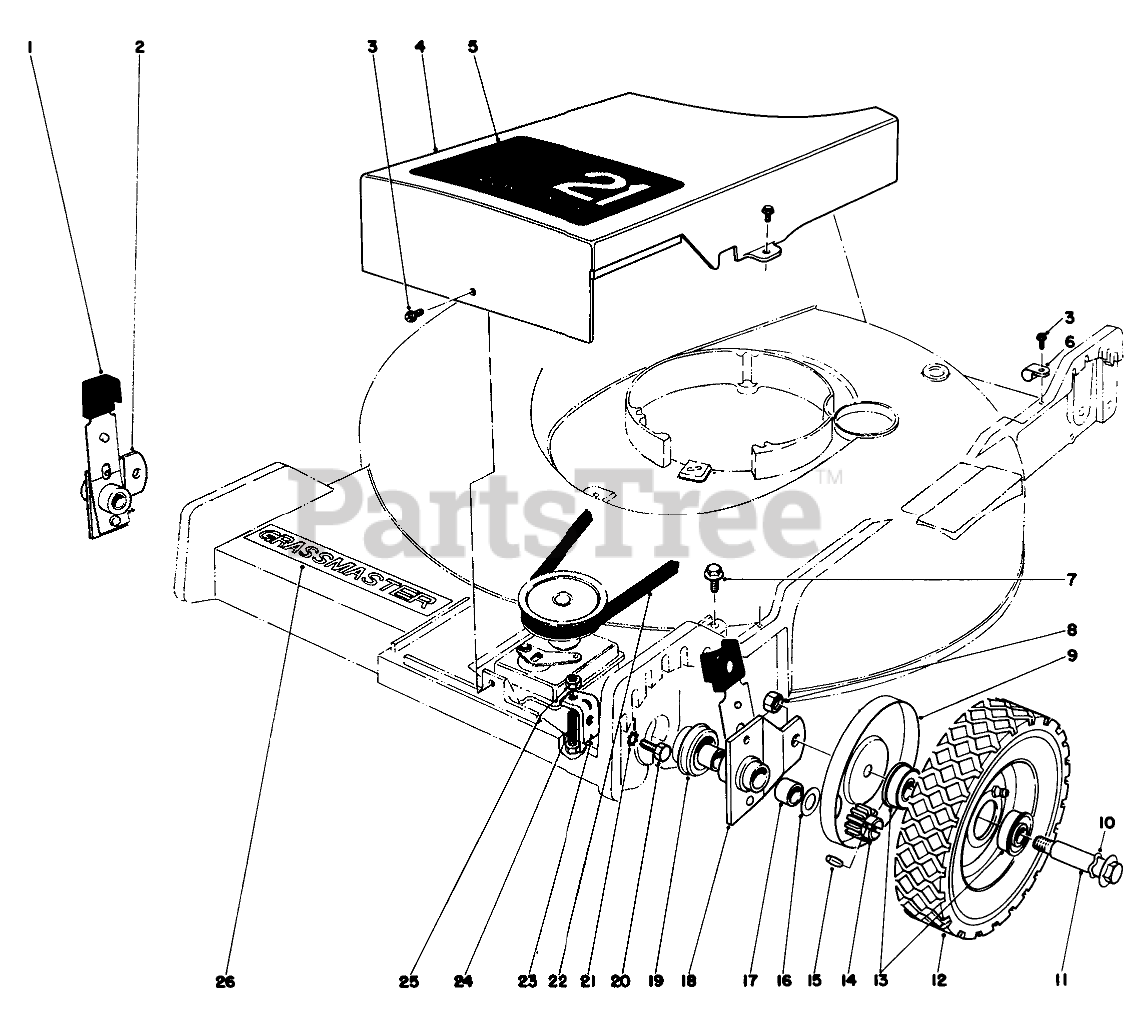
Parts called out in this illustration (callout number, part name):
1	KNOB-ARM
2	Pivot Arm (Incl. Ref. #17)
3	SCREW
4	Belt Cover
5	Decal Belt Cover
6	CLAMP-NYLON
7	SCREW-HWHTF
8	Nut
9	WHEEL COVER
10	SPRING WASHER
11	WHEEL BOLT
12	Wheel & Tire Assembly (Incl. Ref. #13)
13	BEARING-BALL
14	Pinion
15	PIN-GROOVED
16	WASHER-THRUST
17	BUSHING
18	Pivot Arm (Incl. Ref. #17)
19	End Cap
20	SCREW-HH
21	WASHER-LOCK
22	V-BELT
23	Bracket-Gear Box
24	SCREW
25	NUT-LOCK
26	Decal Grassmaster
